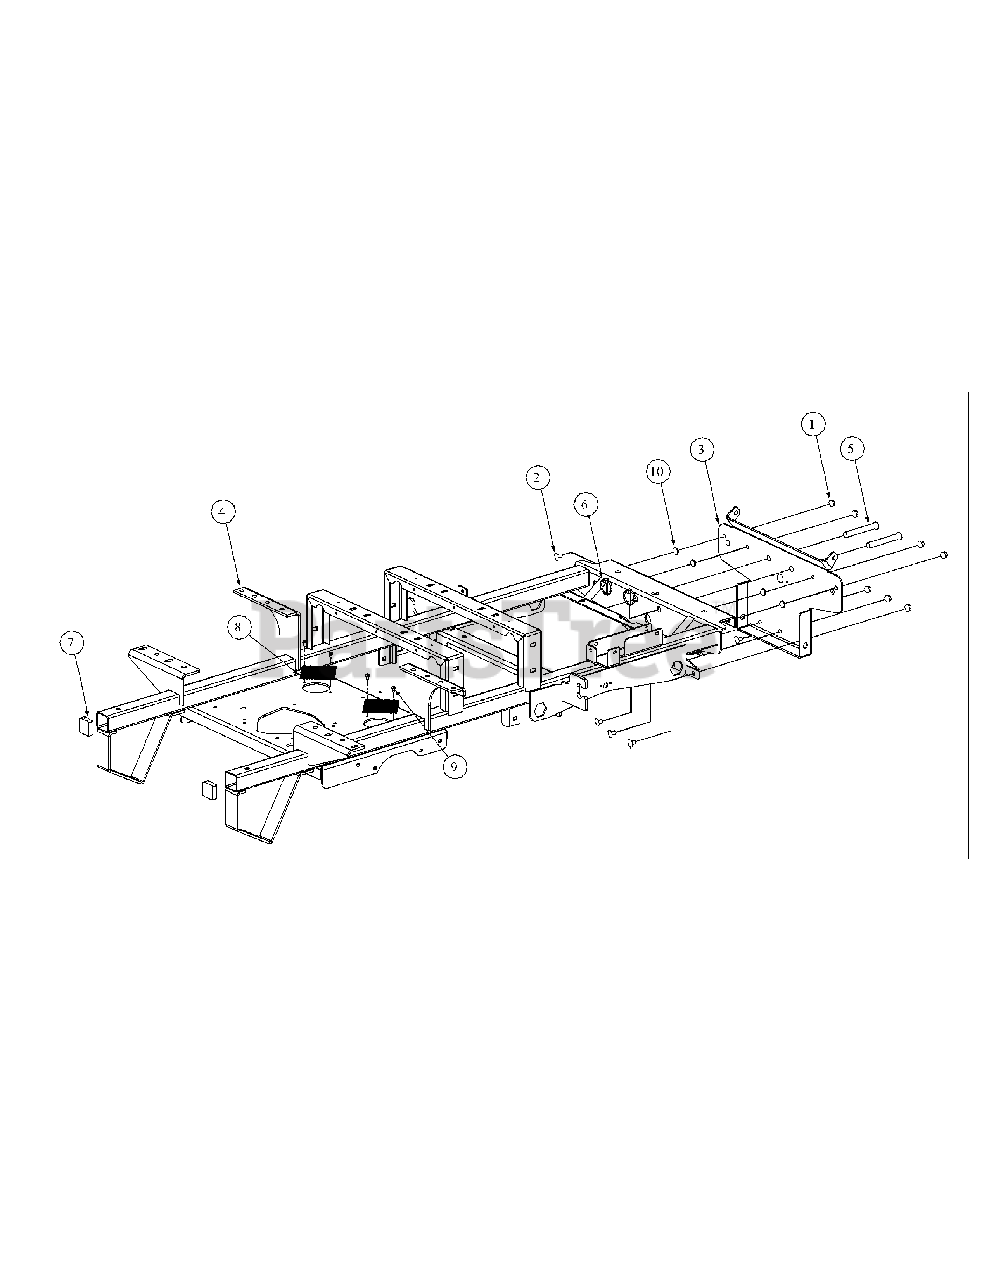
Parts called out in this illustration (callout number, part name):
1	Hex Nut, 3/8-16 Flange Lock
2	Carriage Bolt, 3/8-16 x .75 Long
3	Bracket Assembly, Frame, Front
4	Frame Assembly
5	Clevis Pin, .625 Dia x 4.375 Long
6	Linch Pin, 3/16 Dia.
7	Plug, Square Tube
8	Cover, Hydro Fan
9	Screw, TT, 1/4-20, 0.5
10	Push Retainer, 3/8
